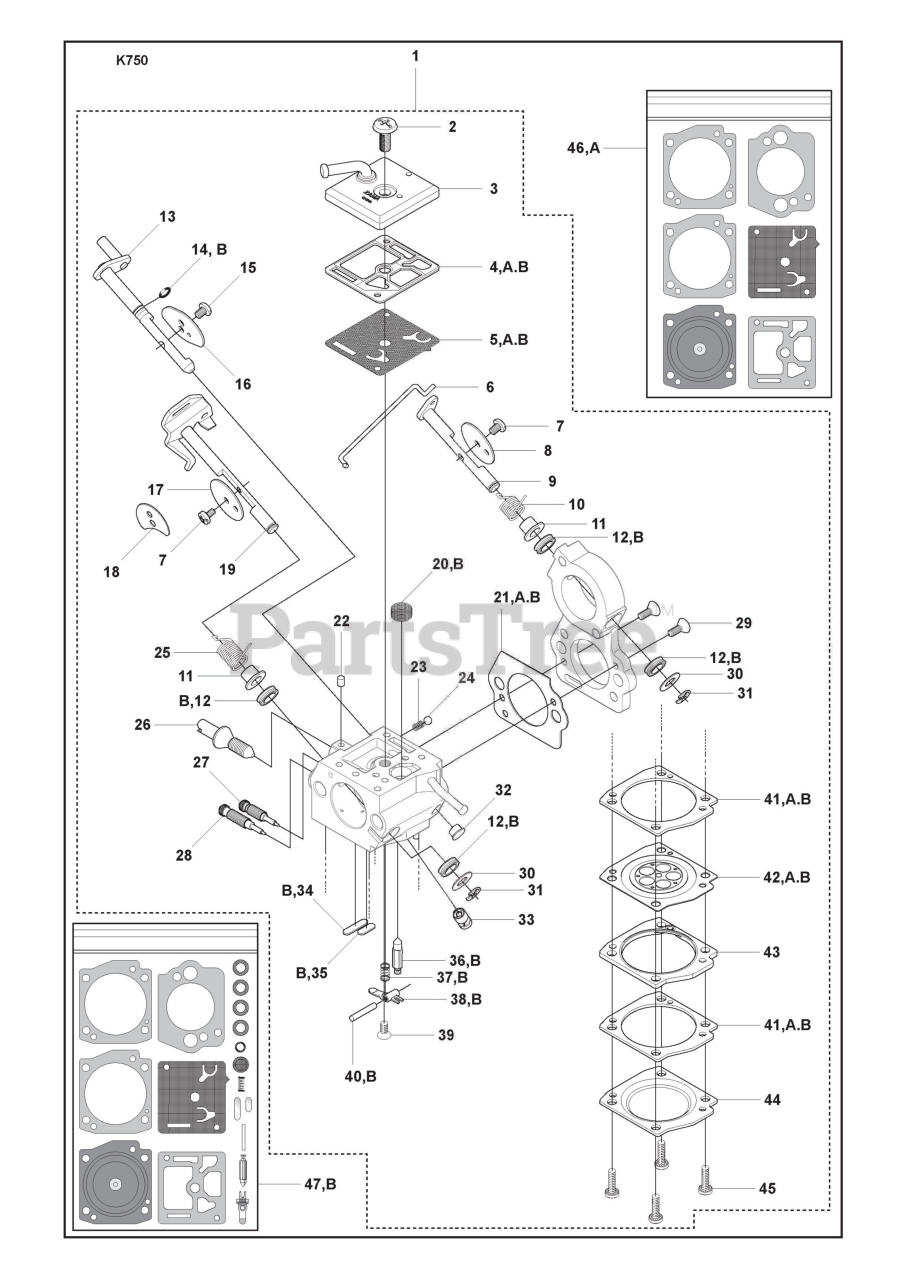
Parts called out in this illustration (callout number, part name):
1	CARBURETTOR
3	PUMP COVER
4	GASKET PUMP
5	DIAPHRAGM PUMP
9	SHAFT ASSY
13	SHAFT ASSY CHOKE
18	VALVE
19	SHAFT ASSY
33	NOZZLE ASSY
34	PLUG WELCH
40	PIN RETAINING SCREW
42	DIAPHRAGM ASSY
46	GASKET KIT
47	GASKET KIT CARB
